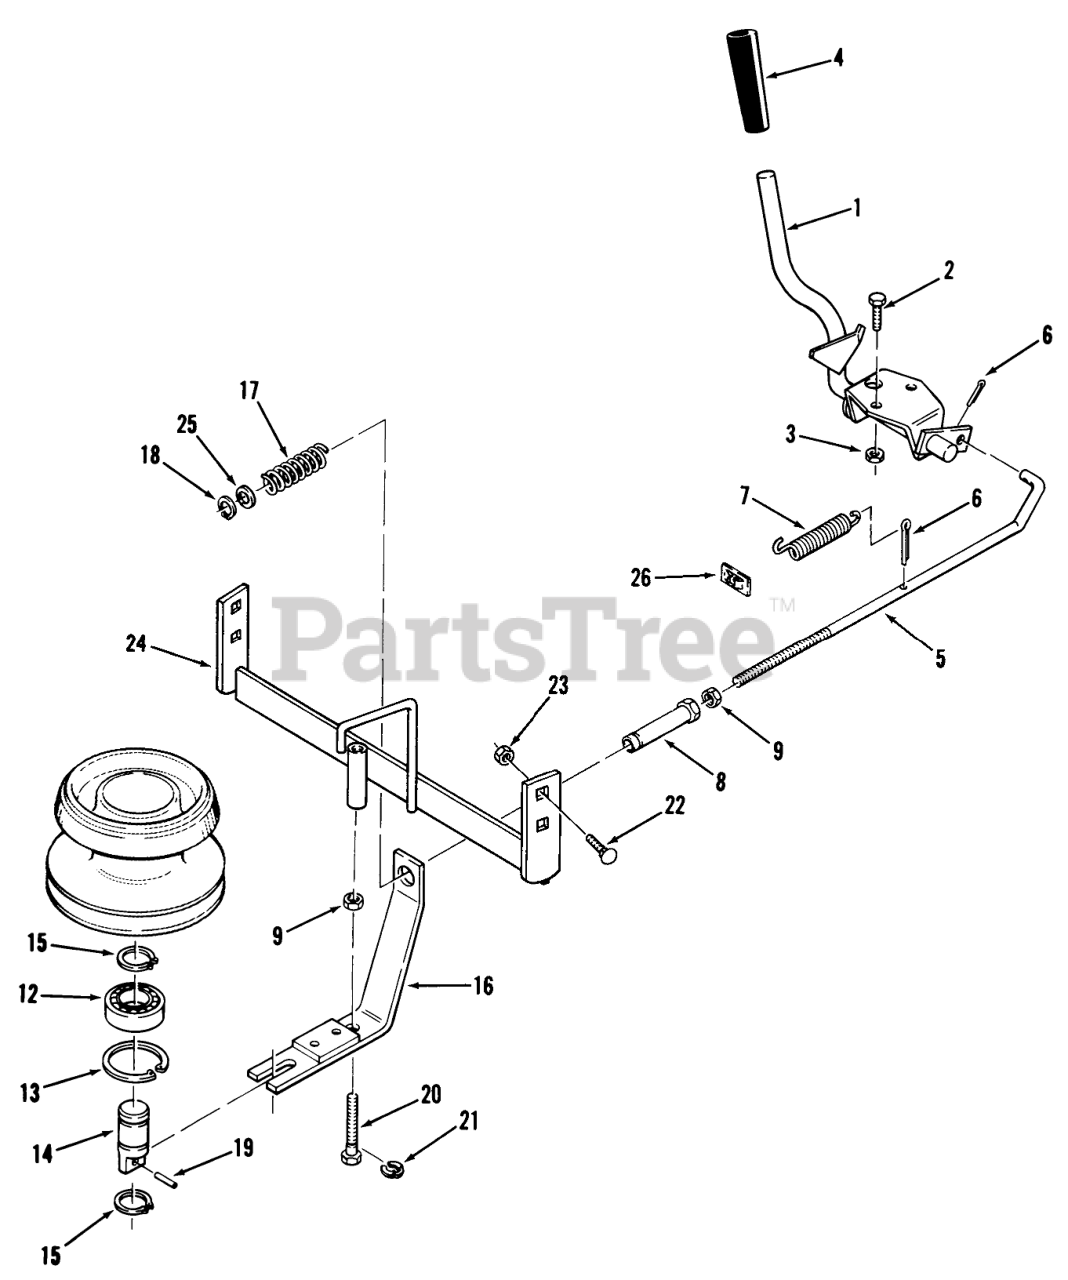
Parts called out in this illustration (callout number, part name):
1	ASSY-HANDLE
2	Bolt
3	Nut
4	GRIP
5	PTO Clutch Rod
6	Cotter Pin
7	Spring
8	TUBE-CLUTCH SPACER
9	Jam Nut 5/16-18
12	BaIl Bearing
13	Ring-Snap
14	Shaft Clutch Hsg
15	RING-SNAP, EXTERNAL
16	ASM-CLUTCH BRAKE PTO
17	SPRING-CLUTCH
18	Retaining Ring
19	SPIROL PIN 7/32X7/8
20	SCREW-CLUTCH ADJUST
21	E-Ring
22	Bolt
23	Nut
24	Clutch Mounting Bracket 216-5 Only
24	Clutch Mounting Bracket
25	Washer
26	SPEED NUT
